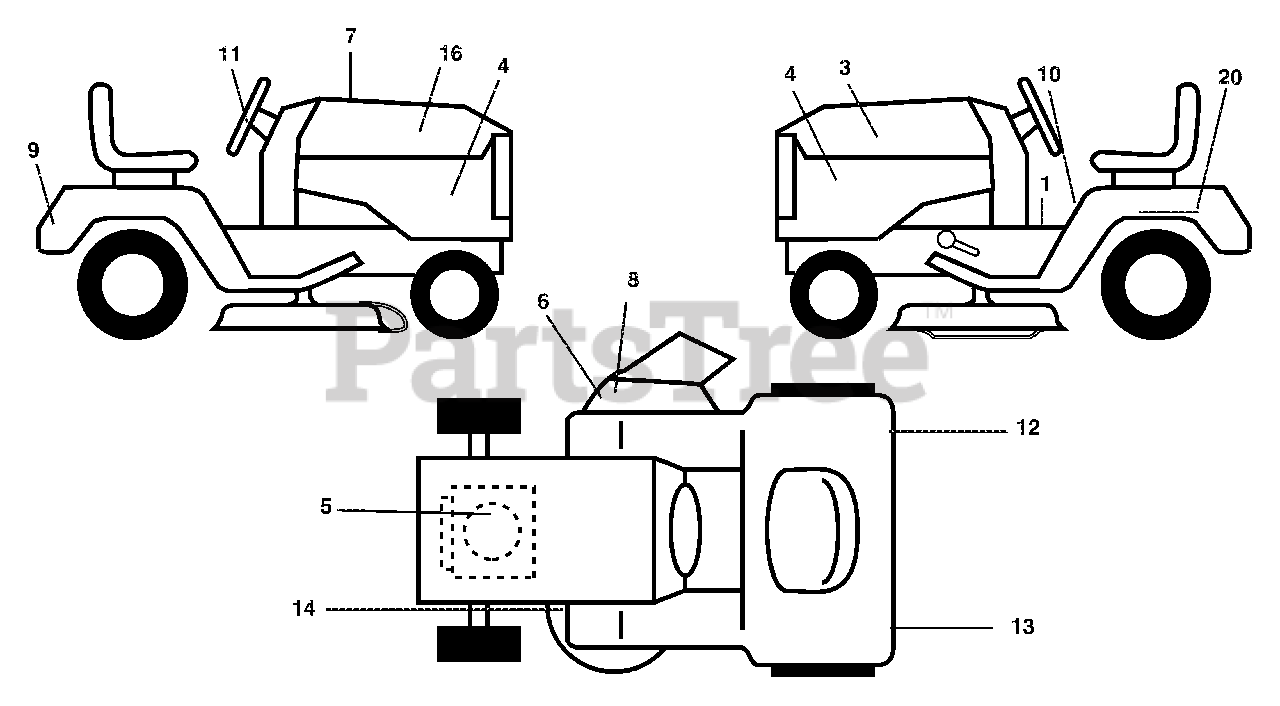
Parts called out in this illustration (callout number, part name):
1	Decal Oper
3	Decal Hood LH
4	Decal Side Panel Logo
5	Decal HP Engine
6	Decal Warning, Keep Hand Away
7	Decal Replacement Parts
8	Decal Deck "B" 42"
9	Decal Fender Logo
10	Decal Fender Danger E/F
11	Decal Ins Strg Whl
12	Decal Fend Reflector Rh
13	Decal Fend Reflector Lh
14	Decal V-Belt Schematic
16	Decal Hood Rh
20	Decal Bat Dan/Psn
